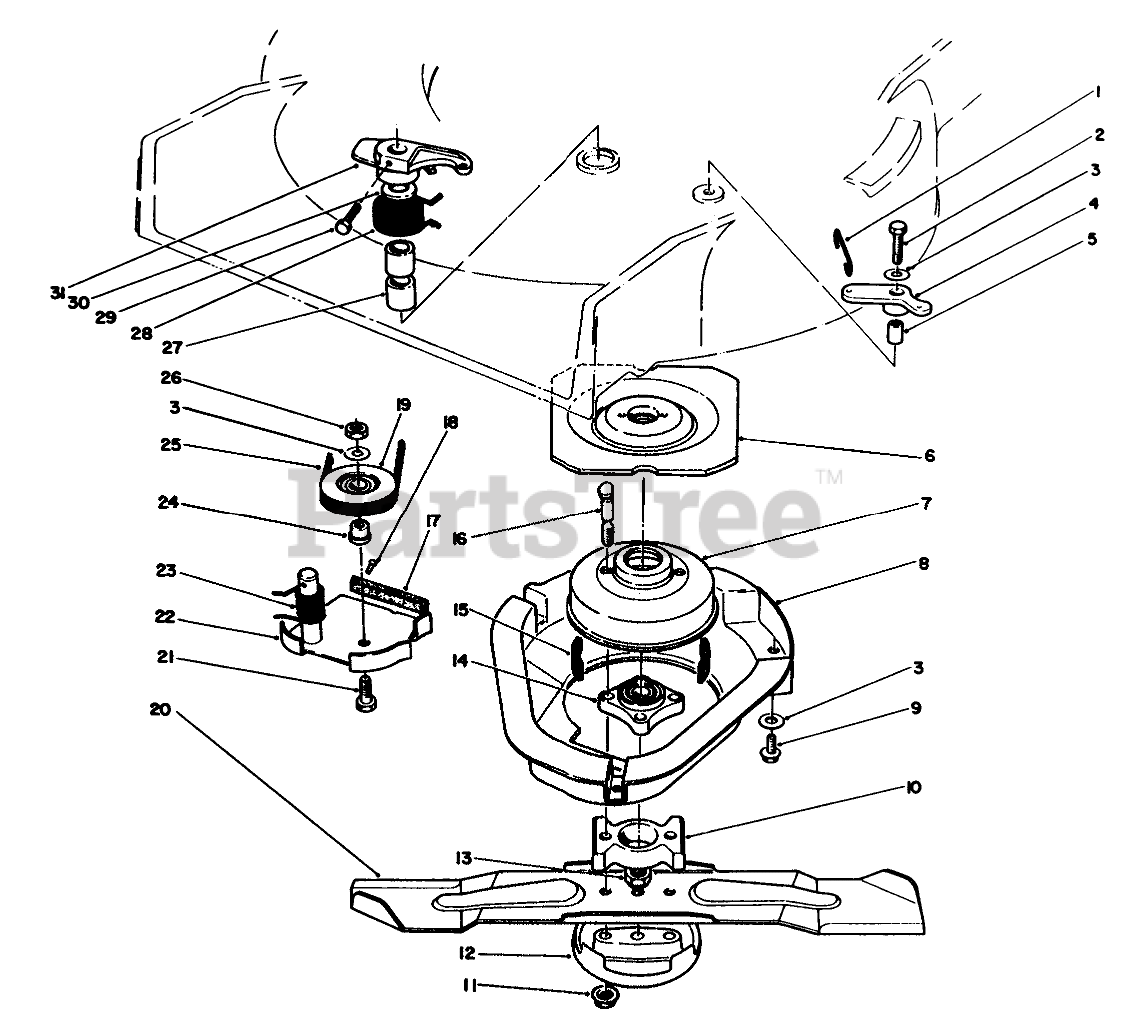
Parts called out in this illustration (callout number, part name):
1	LINK-CONTROL
2	SCREW-HH
3	WASHER-PLAIN
4	BELLCRANK
5	SLEEVE-BELLCRANK
6	Flywheel
7	Drum-Brake
8	SHIELD BBC
9	SCREW-HWHTF
10	SPACER-BLADE
11	NUT-LOCK
12	Anti Scalp Cup
13	NUT-LOCK, NI
14	HUB ASM
15	DAMPENER-VIBRATION
16	BOLT-BLADE
17	Pad-Brake
18	.185 DIA X .375 RT +
19	PULLEY-IDLER
20	BLADE-21in
21	SCREW-HH
22	Brake Plate (Incl. Ref. #17 & 18)
23	SPRING-TORSION
24	HUB-PULLEY, IDLER
25	V-BELT
26	NUT-LOCK, NI
27	BEARING
28	SPRING-TORSION
29	SCREW-HH
30	WASHER
31	LEVER
